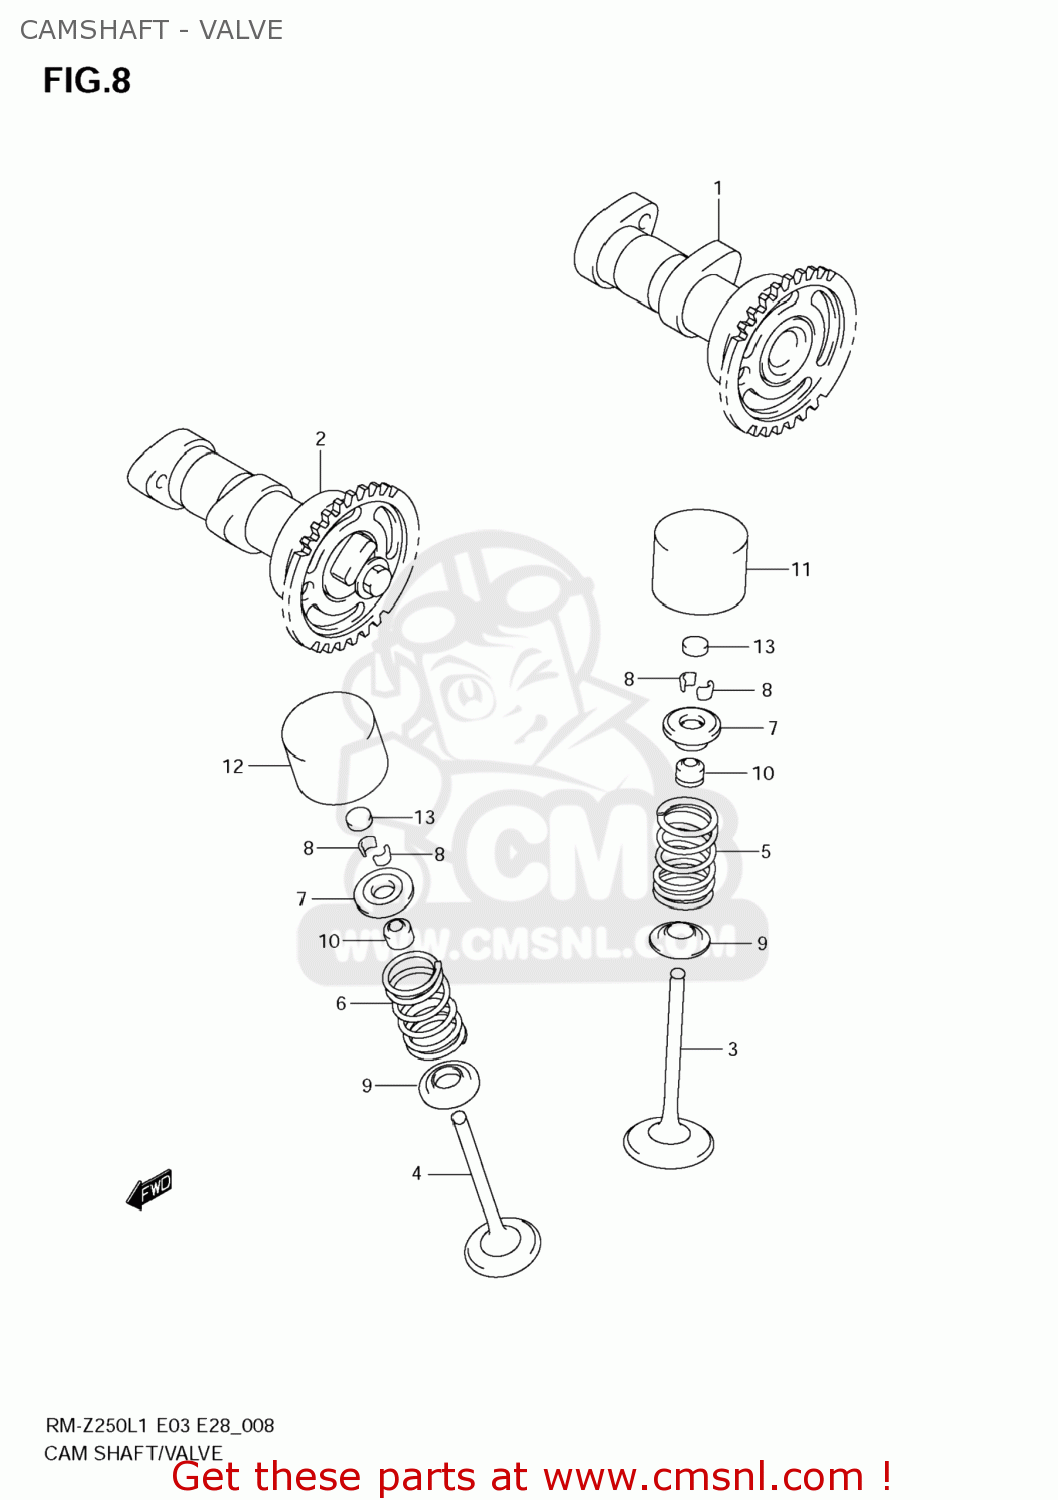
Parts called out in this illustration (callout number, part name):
1	CAMSHAFT,INTAKE
2	CAMSHAFT,EXHAUST
3	VALVE,INTAKE
4	VALVE,EXHAUST
5	SPRING,VALVE
6	SPRING,VALVE
7	RETAINER,VALVE SPRING
8	COTTER VALVE
9	SEAT,VALVE SPRING
10	SEAL,OIL(4.5X10X8)
11	TAPPET
12	TAPPET,EXHAUST
13	SHIM,TAPPET
14	SHIM SET,TAPPET
15	CASE,TAPPET SHIM
